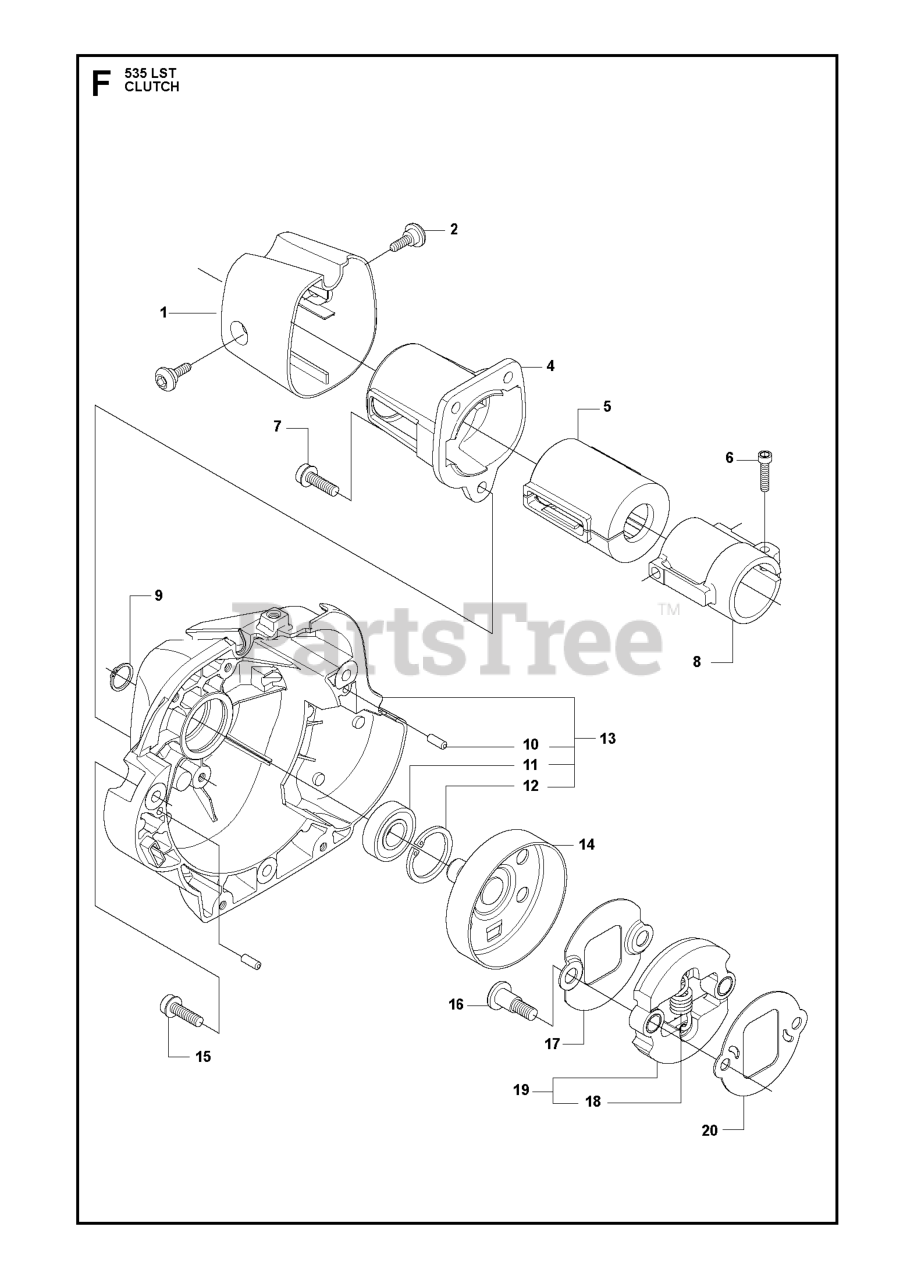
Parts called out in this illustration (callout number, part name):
1	BATTERY 12V .35 AMP
2	BOLT.HEX.1/4.X.3/4.DICHROMATE
8	BATTERY TRAY T
10	BOLT 1/4-20 X 7.5
11	BATTERY HOLDDOWN FRONT MOUNT
12	NUT, PUSH NYLON 1/4" BATTERY
16	SWITCH INTERLOOK PUSH-IN
21	HARNESS.W/LIGHT SOCKET
25	CABLE, BATTERY
27	NUT
28	CABLE, GROUND
29	PLUNGER SWITCH (COLOR:OLIVE)
30	IGNITION SWITCH
33	KEY MLD GEN DELTA
40	HARNESS, IGNITION
42	COVER.TERMINAL.RED
46	HOUR METER
50	RP.PTO.SWITCH.8 TERMINAL.BLACK
79	BULB HOLDER ASM.
81	RELAY.ASSY.T
89	BRACKET SNAP-IN HOURMETER
